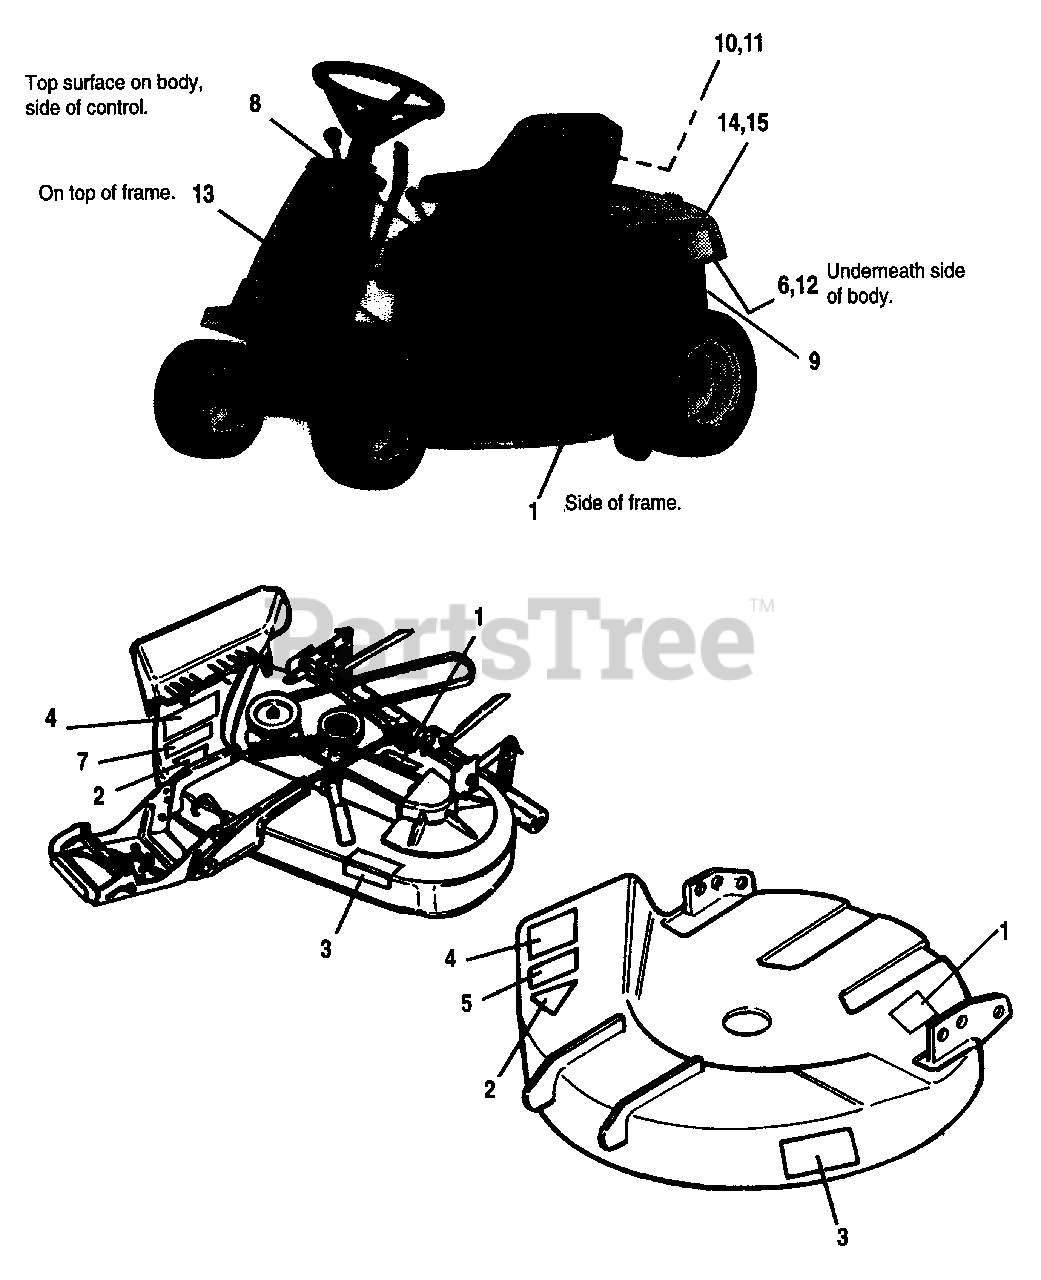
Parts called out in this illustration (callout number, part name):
1	I.D. PLATE
2	DECAL, OPEI
3	DECAL, Danger (Hand Under Deck)
4	DECAL, Danger (Chute In Place)
5	DECAL, Cutting Width-30"
6	DECAL, Belt & Blade Replacement
7	DECAL, Cutting Width-34"
8	DECAL, Throttle/Choke
9	DECAL, Transmission Release Valve (Hydro models only)
10	DECAL, Logo, AGCO Allis
11	DECAL, USA (Seat back)
12	DECAL, Touch-up Paint
13	DECAL, Operating Instructions
14	DECAL, Seat Deck, LH (409G)
14	DECAL, Seat Deck, LH (412G)
14	DECAL, Seat Deck, LH (412H)
14	DECAL, Seat Deck, LH (413H)
15	DECAL, Seat Deck, RH (409G)
15	DECAL, Seat Deck, RH (412G)
15	DECAL, Seat Deck, RH (412H)
15	DECAL, Seat Deck, RH (413H)
